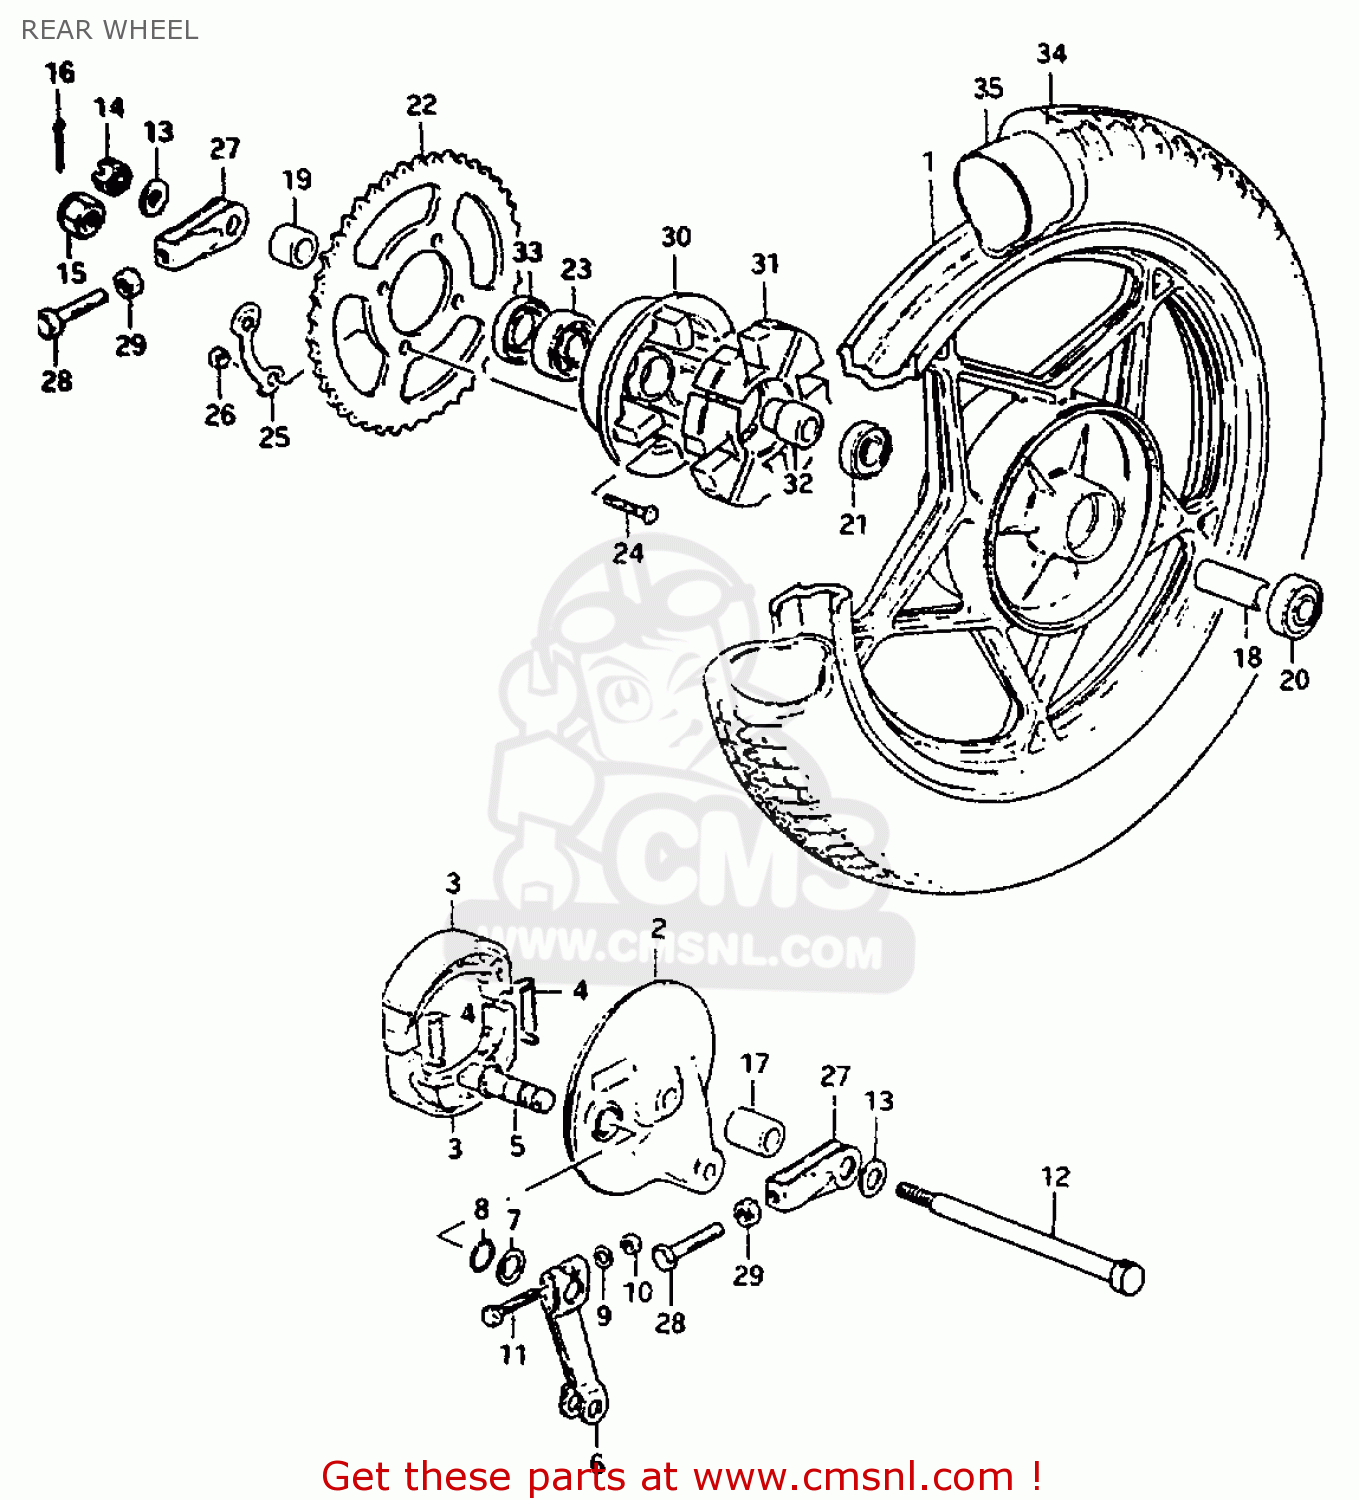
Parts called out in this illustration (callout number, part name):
1	WHEEL, REAR (140X18)
2	PANEL, REAR HUB
3	SHOE,BRAKE
4	SPRING(L:34)
5	CAM,FRONT BRAKE
6	LEVER,RR BRAKE CAM
7	WASHER (14.5X22X1.6)
8	O-RING (D:2.4 ID:13.8)
9	WASHER
10	NUT
11	BOLT(6X33)
12	AXLE,FRONT
13	WASHER
14	NUT 12MM
16	COTTER PIN
17	SPACER, AXLE RH
18	SPACER (12.6X19X58)
19	SPACER 12X25X2
20	BEARING
21	BEARING
22	SPROCKET,RR(NT:45)
23	BEARING
24	BOLT(8X33.5)
25	WASHER
26	NUT
27	ADJUSTER,CHAIN,R
28	BOLT(6X38)
29	NUT
30	DRUM,RR SPROCKET MOUNTING
31	CUSHION,REAR DRUM
32	RETAINER,RR SPROCKET DRUM
33	SEAL OIL(25X40X6)
34	TIRE (2.50-18)
35	TUBE,INNER
